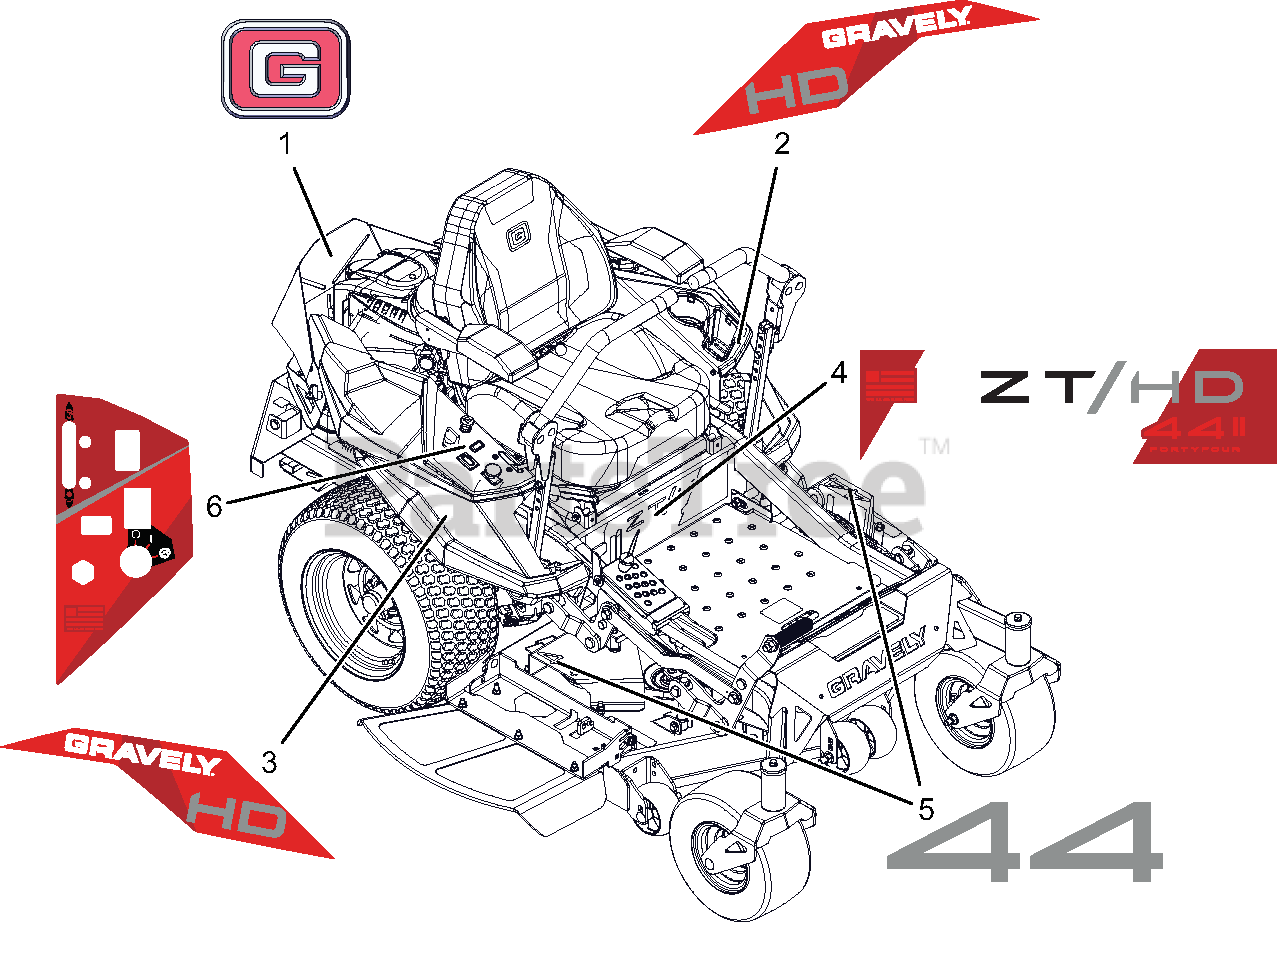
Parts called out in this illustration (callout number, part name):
1	DECAL, GRAVELY BRAND
2	DECAL, FENDER LH - HD
3	DECAL, FENDER RH - HD
4	DECAL, ZT/HD - 44
5	DECAL, DECK - 44
6	DECAL, CONTROL PANEL
